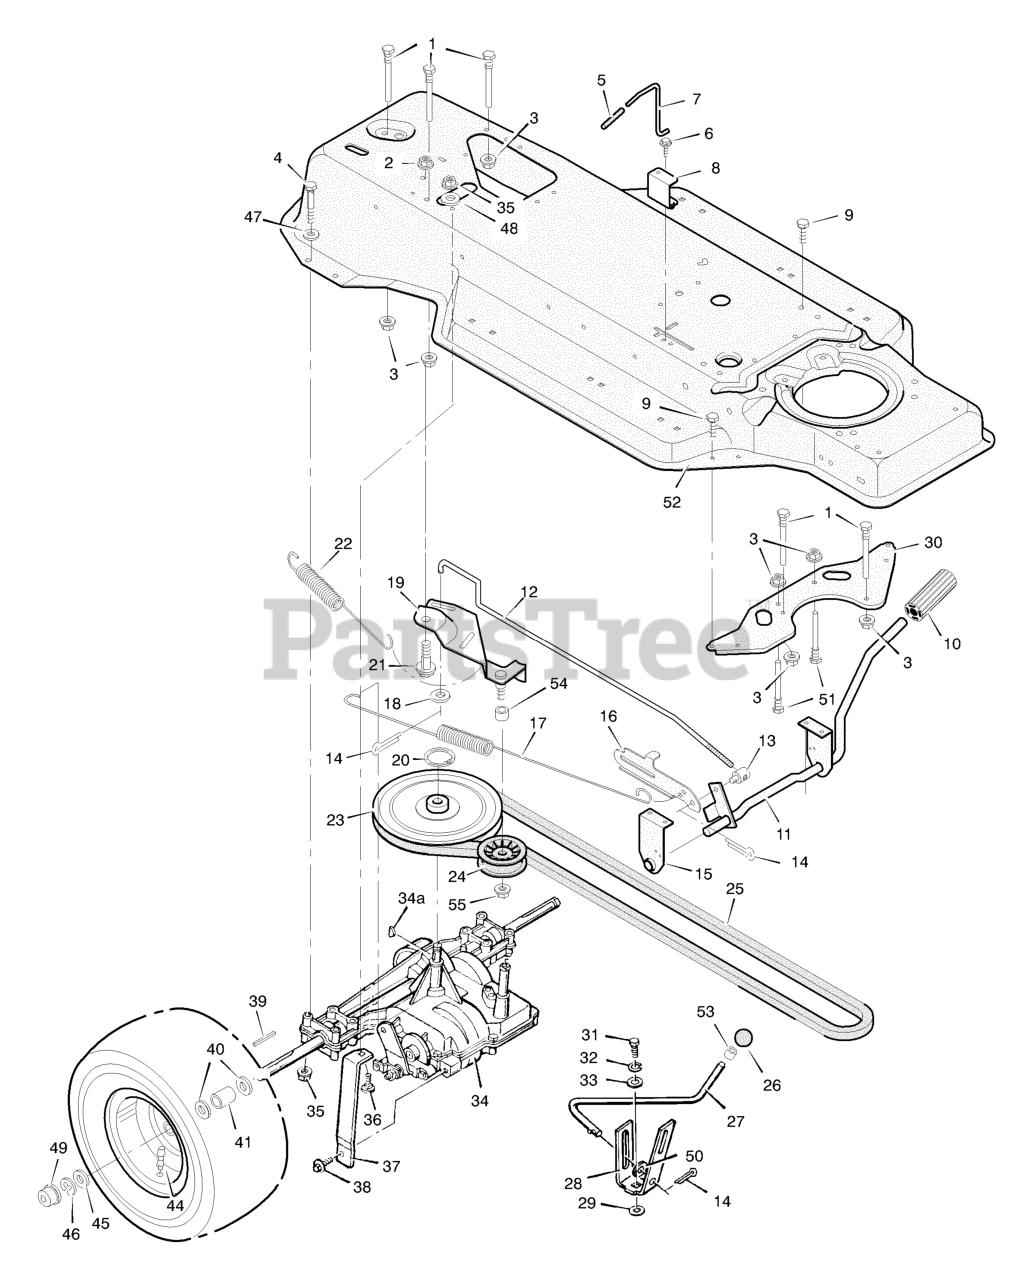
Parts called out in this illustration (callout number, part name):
1	Guide, Belt
2	Locknut, Flange
3	Nut, Flange
4	Bolt, Hex
7	Rod, Control -Park Brake
8	Guide, Bracket
10	Clutch and Brake Pedal
11	Lever Assembly
12	Rod, Clutch
13	Nut, Adjustable
14	Pin, Cotter
15	Bracket, Support
16	Latch, Park Brake
17	Spring, Brake Extension
18	Washer
19	Bracket Assembly, Idler
20	Ring, Retainer
21	Bolt, Shoulder
22	Spring, Drive Extension
23	Pulley, Motion Drive
24	Pulley, Backside Idler
25	Belt, Motion Drive
26	Knob, Shift Lever
27	Lever, Shift
28	Yoke, Shift
30	Plate, Belt Guide
31	Bolt, Hex
32	Lockwasher
34	Transaxle, Dana 4360-190 **
35	Nut, Flange
36	Bolt, Carriage
37	Support, Transaxle
39	Key, Square
41	Spacer, Transaxle
43	Wheel & Tire Assembly
44	Stem, Valve
47	Washer
49	Hub Cap
50	Washer
51	Guide, Belt
52	Frame Assembly
53	Ring, Tolerance
55	Nut
